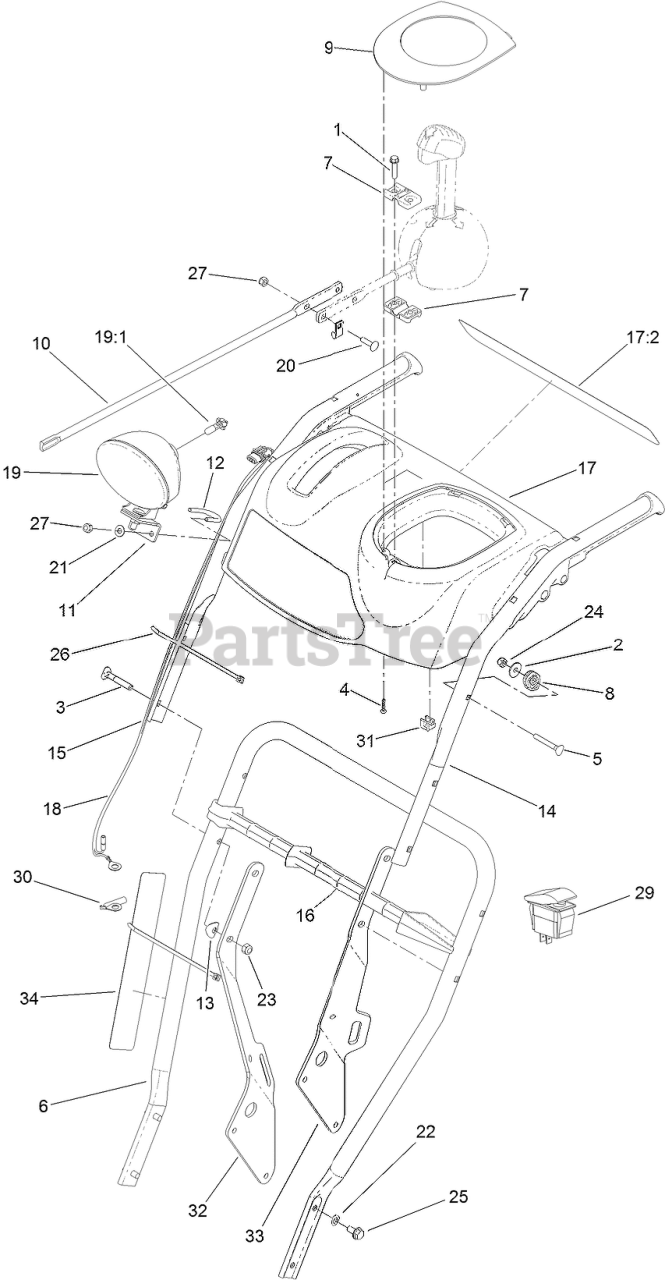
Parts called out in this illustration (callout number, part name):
1	SCREW-PLASTITE
2	WASHER-PLAIN
3	SCREW-HANDLE
4	SCREW-PPH
5	SCREW
6	HANDLE-LOWER
7	SUPPORT-ROD
8	CLAMP-CABLE
9	COVER-PANEL, CONTROL
10	ROD-CHUTE, FRONT
11	BRACKET-LIGHT
12	CLAMP-LIGHT
13	WASHER
14	HANDLE-UPPER, LH
15	HANDLE-UPPER, RH
16	STICK-CLEANOUT
17	CONTROL PANEL ASM
17:2	DECAL-CONTROL
18	HARNESS-WIRE, HEATED GRIPS
19	HEADLAMP ASM
19:1	LAMP-12 VOLT
20	SCREW-CARR
21	WASHER-FLAT
22	WASHER-BELLEVILLE
23	NUT-LOCK, NI
24	NUT-LOCK, NI
25	SCREW-HWHTF
26	TIE-CABLE
27	NUT-LOCK, NI
29	SWITCH-ROCKER, OFF-NONE-ON
30	HARNESS-WIRE, GROUND JUMPER
31	CLIP-EDGE
32	BRACE-HANDLE, LH
33	BRACE-HANDLE, RH
34	DECAL-TAPE, REFLECTIVE
